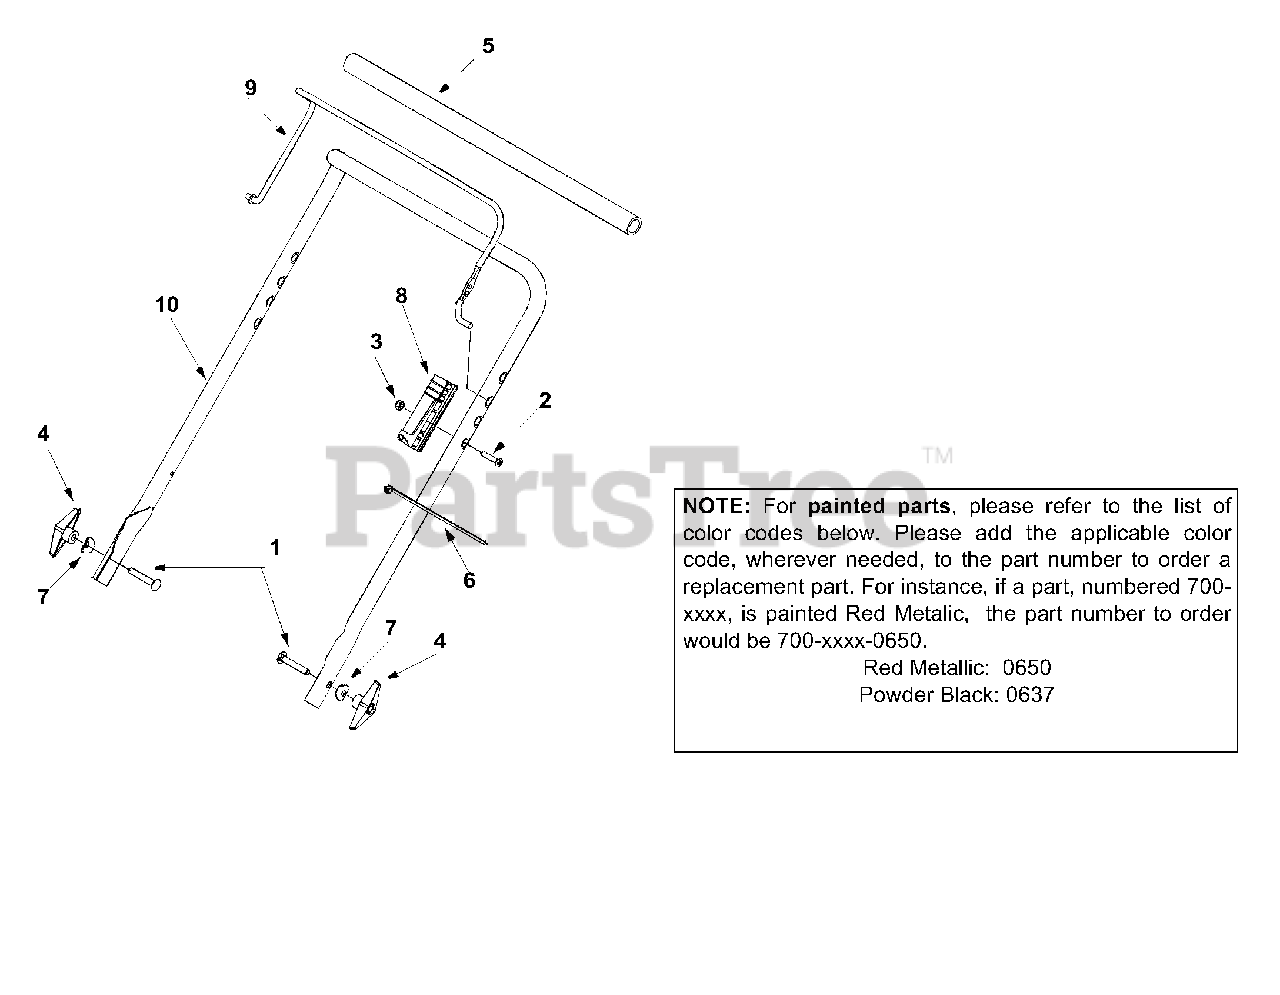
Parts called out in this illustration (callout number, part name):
1	Carriage Screw 5/16-18 x 2.0"
2	Machine Screw
3	Hex Lock Nut 1/4-20
4	Hand Knob w/ Wing Nut
7	Saddle Washer
8	Control Housing
